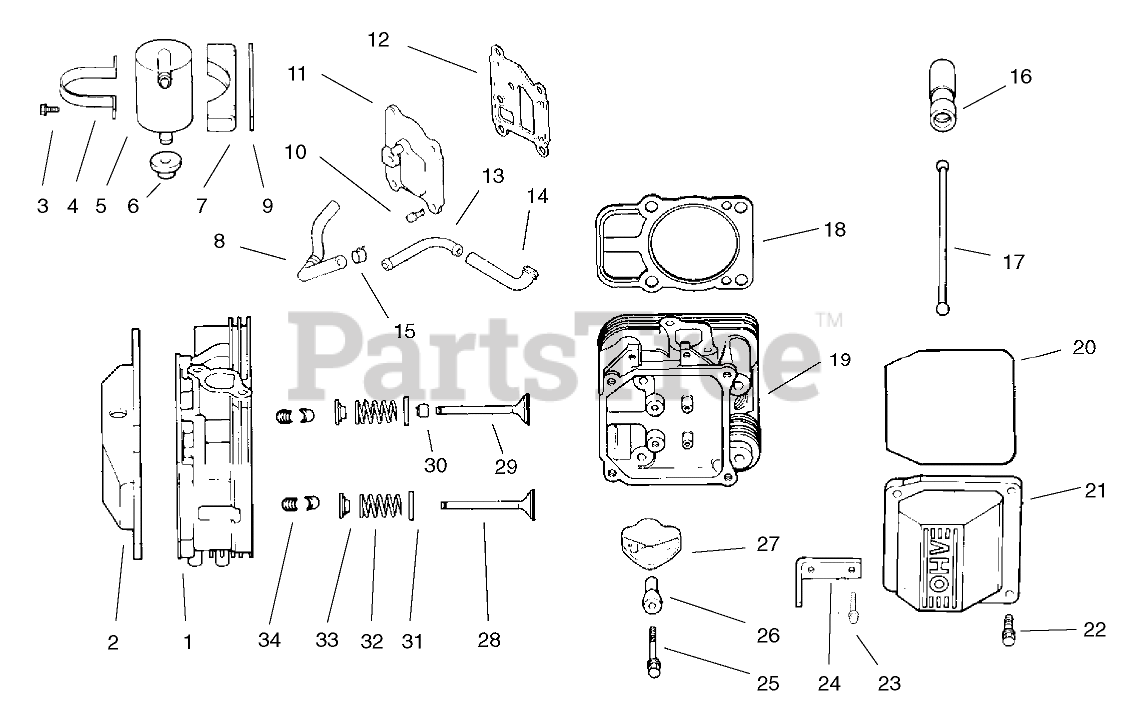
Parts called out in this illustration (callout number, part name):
1	#1 Cyl. Head Asm
2	Kit-Valve Incl 6 20-22
3	Screw-HF
4	Strap-Lifting
5	Kit-Breather Incl 3-9
6	Grommet-Rubber
7	Bracket
8	Hose-Breather
9	Spacer
10	Screw
11	Cover-Breather
12	Gasket-Breather
13	Fitting
14	Hose-Breather
15	Clamp
16	Lifter-Valve
17	Rod-Push
18	Gasket-Cylinder Head
19	#2 Cyl. Head Asm,
20	O Ring
21	Valve Kit
22	Screw
23	Screw
24	Strap-Lifting
25	Screw
26	Pivot-Arm, Rocker
27	Arm-Rocker
28	Valve-Exhaust
28	Valve-Exhaust (.25)
29	Valve-Intake
29	Valve-Intake (.25)
30	Seal-Stem, Valve
31	Retainer-Spring
32	Spring-Valve
33	Cap-Spring, Valve
34	Retainer Kit
